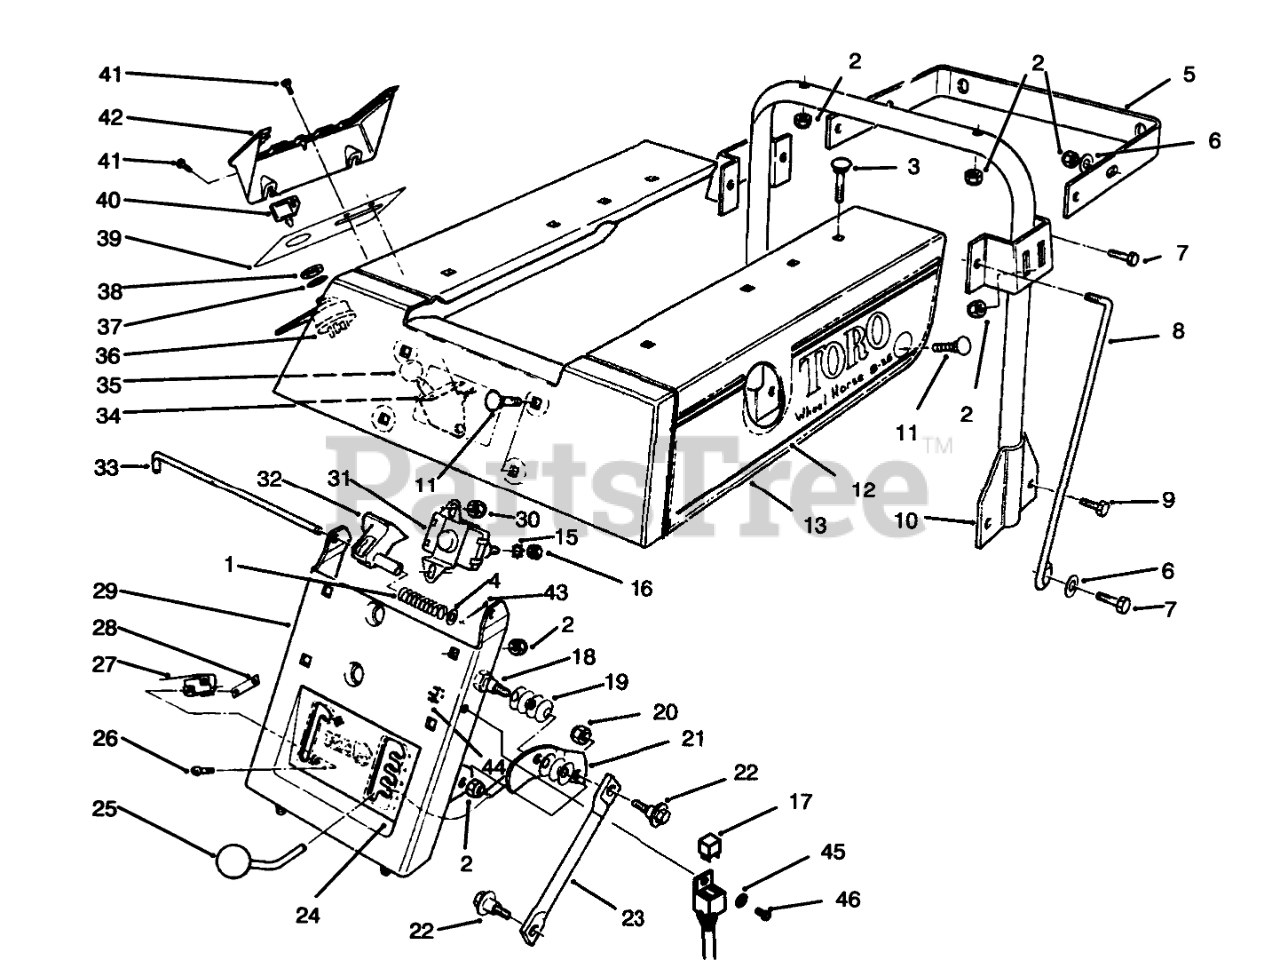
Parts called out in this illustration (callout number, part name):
1	SPRING-COMPRESSION
2	NUT-LOCK, NI
3	SCREW-CARR
4	WASHER-FLAT
5	STANDBAR
6	WASHER-PLAIN
7	SCREW-HH
8	BRACE-SEAT SUPPORT
9	SCREW-HH
10	SEAT SUPT WA (BLACK)
11	SCREW-CARR
12	DECAL - LH SIDE PLATE
13	SEAT BODY WA (RED)
15	WASHER-LOCK
16	NUT-JAM
17	Relay
18	BOLT-SHOULDER
19	WASHER-BELLEVILLE
20	NUT-LOCK, NI
21	HOC HDLE WA
22	BOLT-SHOULDER
23	LINK-HOC
24	DECAL - HOC
25	KNOB-CONTROL
26	SCREW-HH
27	SWITCH-MICRO
28	NUT-SPEED
29	FRT SEAT SUP WA RED
30	NUT-LOCK, NI
31	Solenoid
32	PROP-SEAT
33	ROD-SEAT BASE
34	CONTROL-THROTTLE
35	Knob
36	Switch-Ignition (Incl. Ref. #37 & 38)
37	WASHER-TOOTH, INTERNAL
38	NUT-HH
39	DECAL - CONTROL PANEL
40	KEY-IGNITION
41	SCREW-THD FORM, HWH
42	COVER-CONTROL PLATE
43	PIN-COTTER
44	NUT-LOCK, NI
45	WASHER-FLAT
